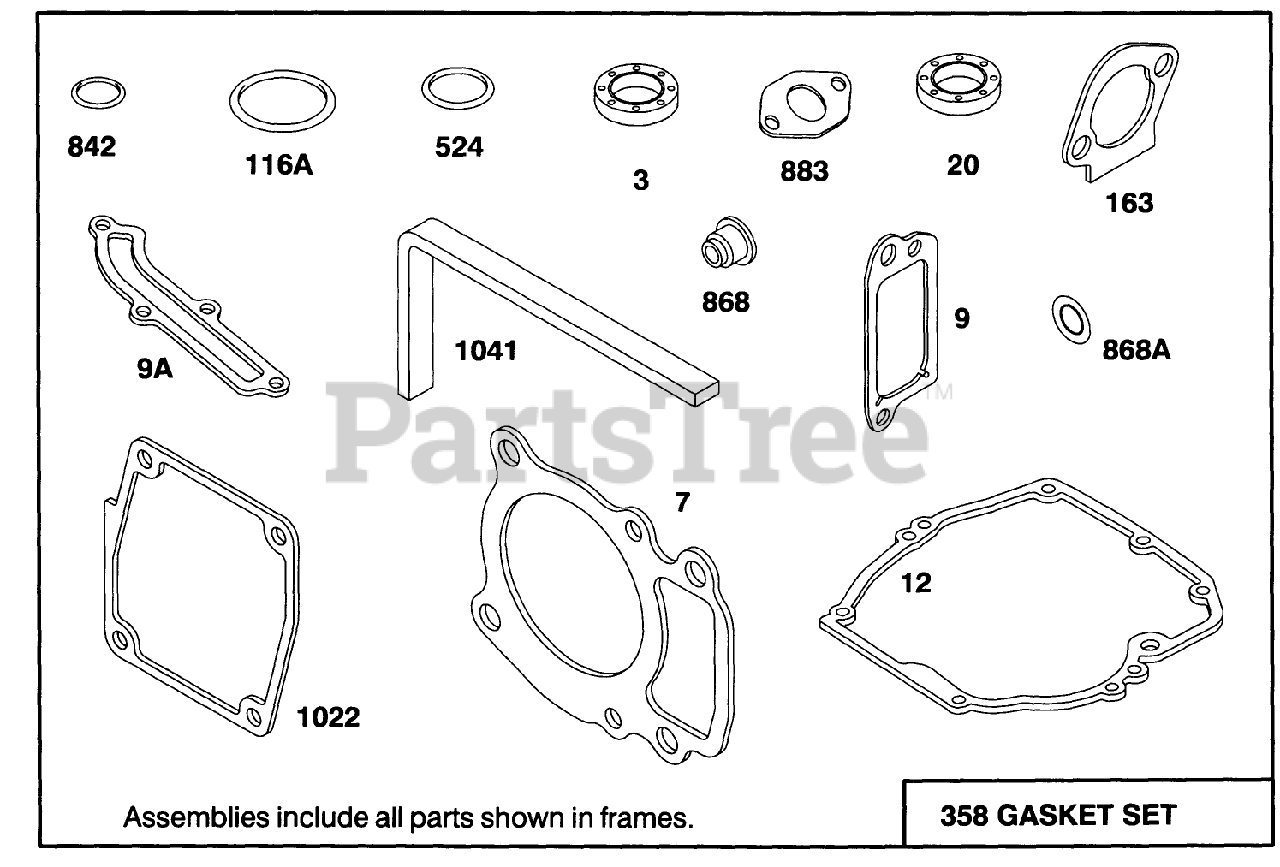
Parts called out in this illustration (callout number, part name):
104	FLOAT HINGE PIN
116	SEALING GASKET
118	VALVE KIT - NEEDLE
121	CARBURATOR OVERHAUL KIT
122	ADAPTER ASSEMBLY
134	Valve-Float (Includes Seat)
137	FLOAT BOWL GASKET
358	GASKET SET
634	SEAL WASHER
977	CARBURATOR GASKET SET
1039	FLOAT LIMITER
